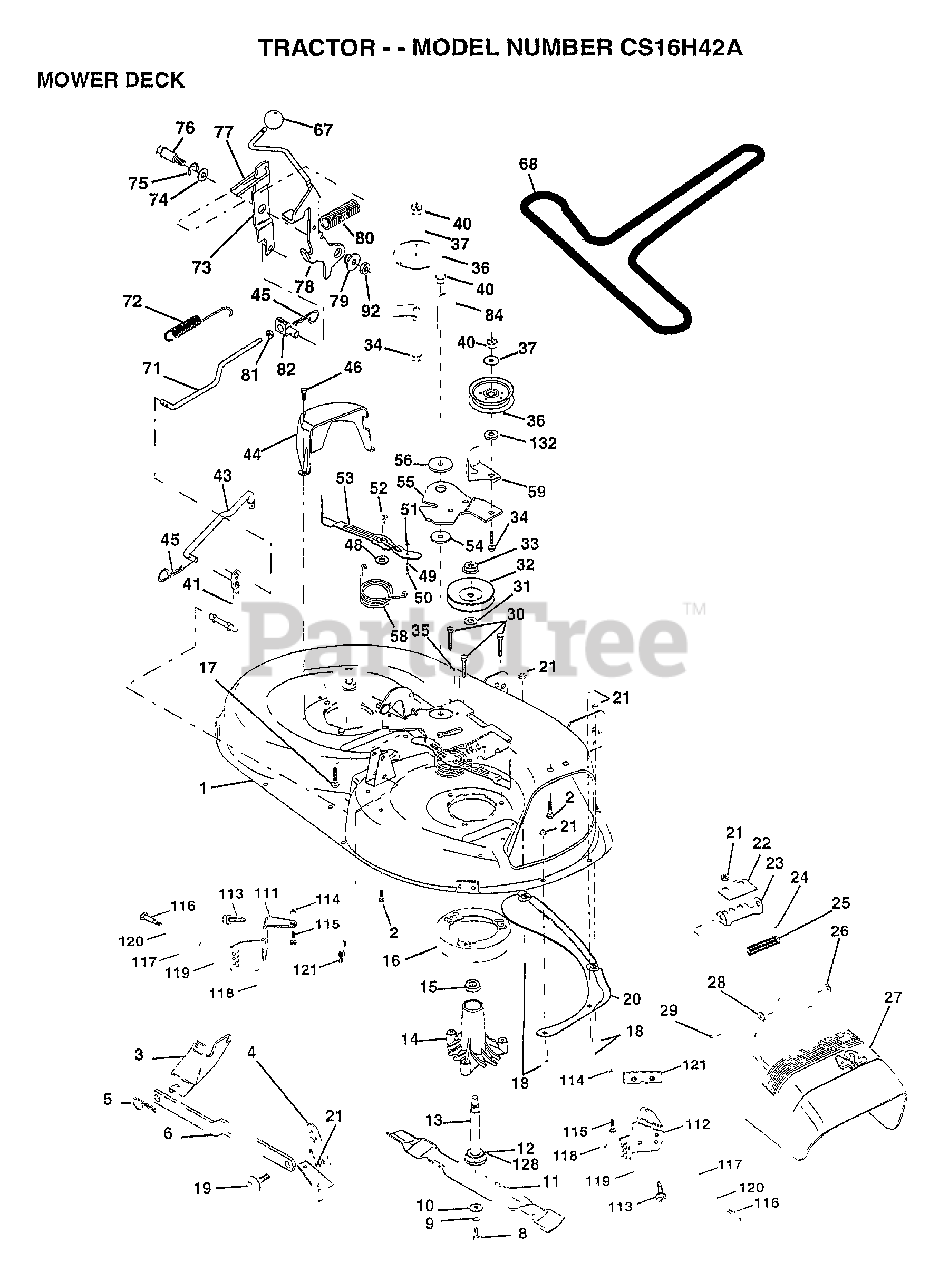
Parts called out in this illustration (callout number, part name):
1	DECK.WELD.42.
2	BOLT
3	BRKT ASM SWAY BAR
4	BRKT DECK SW BAR
8	BLADE BOLT
10	WASHER.HARD.BLADE
11	"BLADE.42"" HIPERF"
12	BEARING.BALL
14	HSG ASM MANDREL
15	BEARING
16	STRIPPER RND MWR
17	BOLT RDHD 3/8-16
18	BOLT
19	BOLT SHD 5/16-18
22	STIFFENER BRKT
23	DEFLECTOR BRKT
24	CAP-SLEEVE LT
25	SPRING TORSION
26	NUT PUSH M
27	DEFLECTOR.SHIELD
28	WASHER
29	HINGE ROD
31	WASHER
32	PULLEY.MANDREL.42
34	BOLT
35	XMAS TREE FASTNER
36	FLAT IDLER PULLEY
37	WASHER
41	PIVOT ROD
43	ROD CLUTCH W/NIBS
44	GUARD MAND LH BLK
45	RETAINER M
46	SCREW.1/4-20X5/8
48	HARD SMALL WASHER
49	ROLLER ASM-CAM
50	SHOULDER BOLT
51	LOCKNUT
52	BOLT.SHLD.5/16-18
54	HARDENED WASHER
55	ARM-IDLER
56	SPACER RETAINER
58	SPRING TORSN BRAK
59	GUARD IDLER TUV
67	KNOB T(3/8 HOLE)
68	BELT-V.SEC.46.KEL
71	ROD CLUTCH 38/42
72	RETURN SPRING
73	CLUTCH ARM SECOND
74	WASHER
75	RING
76	SHOULDER BOLT
77	SPRING KEEPER
78	LEVER ASM-CLUTCH
79	BUSHING
80	SPRING.CLUTCH.MWR
81	TRUNION ADJ
82	NUT
84	BRACKET ASM IDLER
92	NUT
111	BRACKET.GWHL.LH.
112	BRACKET.GWHL.RH.
113	SCREW
116	BOLT M
117	WHEEL.GAGE.BLK.PL
118	LOCKNUT
119	WASHER
120	WASHER
121	BRACKET.EXTRD.GWL
128	WASHER.FELT.
132	WASHER GT
